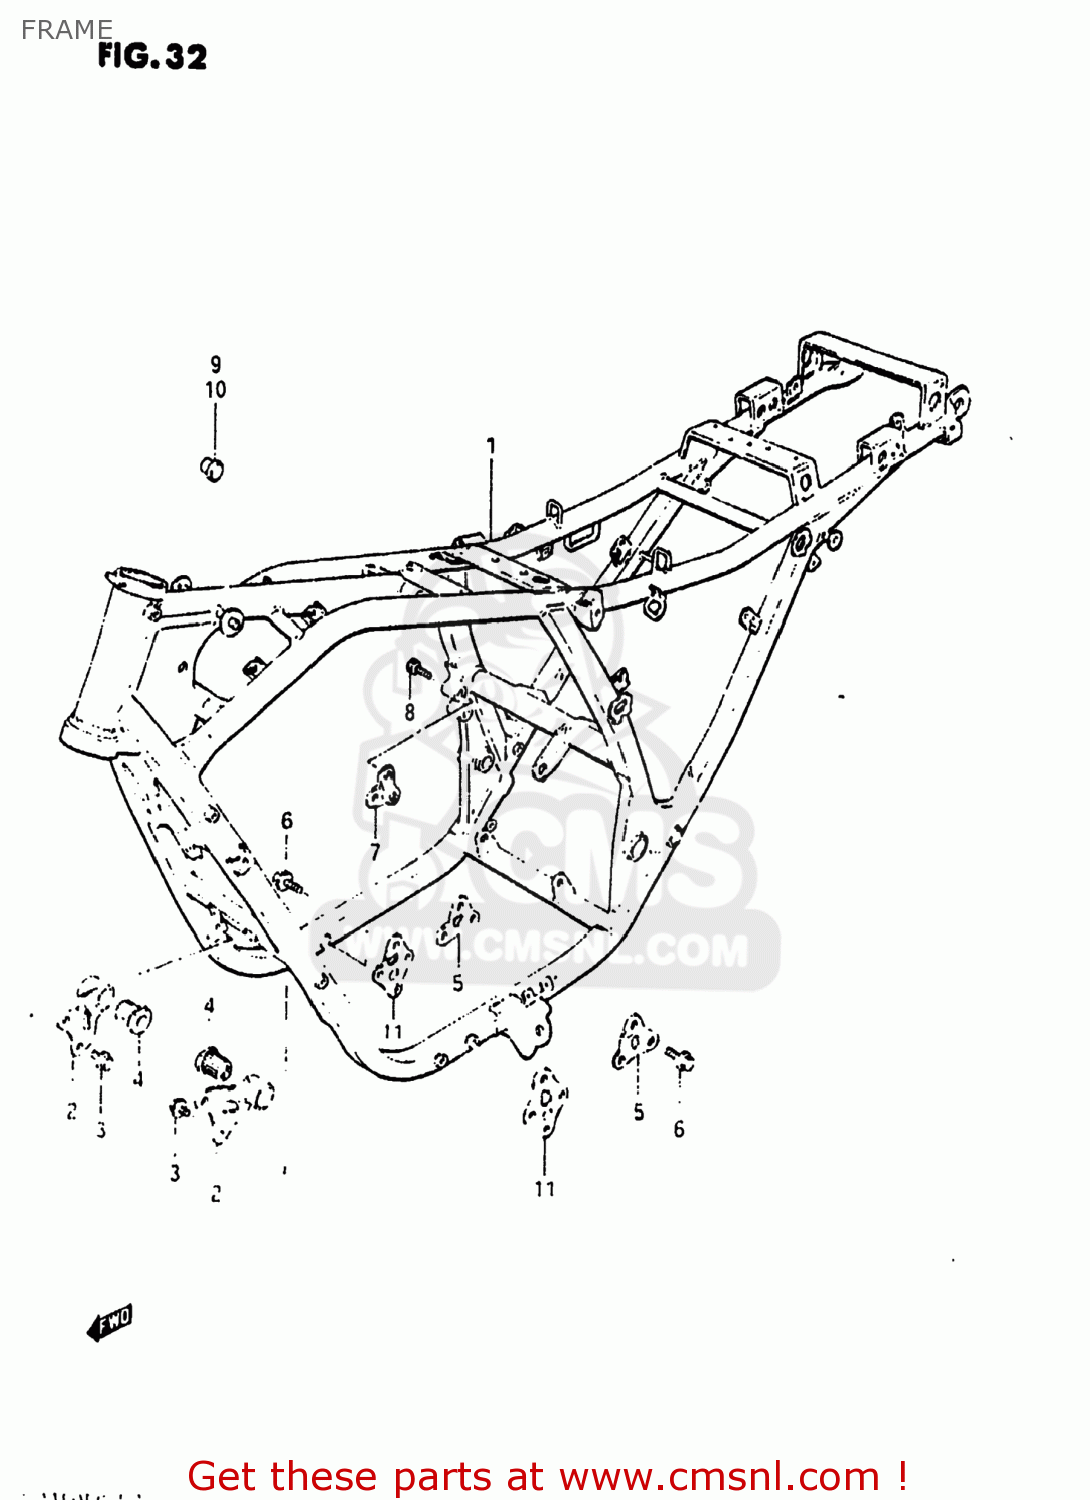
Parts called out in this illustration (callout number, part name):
1	FRAME
2	PLATE,ENGINE MOUNTING NO
3	BOLT
4	BUSH
5	PLATE,ENGINE MOUNTING
6	BOLT
7	PLATE,ENGINE MOUNTING
8	BOLT
9	CAP(OD:10)
10	PLUG
11	PLATE,ENGINE MOUNTING NO
